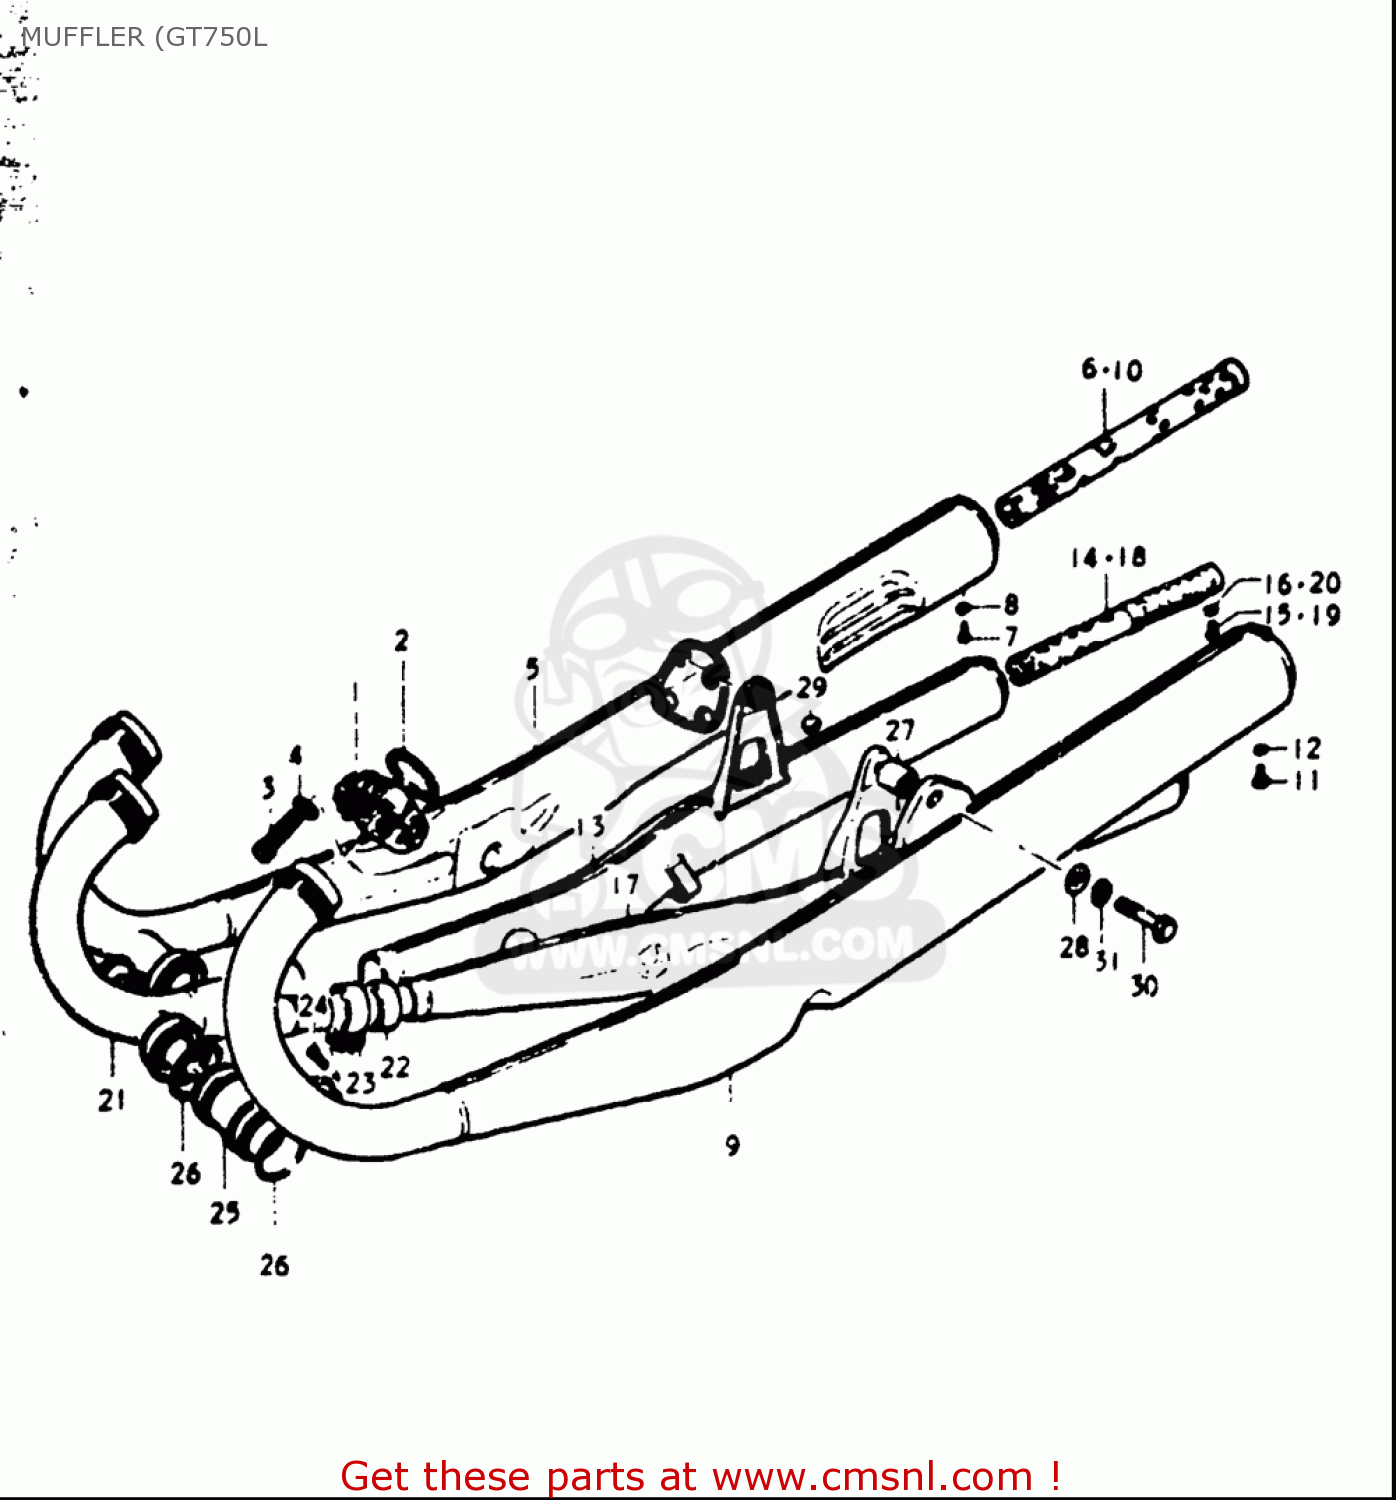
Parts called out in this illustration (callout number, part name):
2	GASKET,EXHAUST PIPE (NAS)
3	BOLT
4	WASHER,LOCK
6	PIPE,BAFFLE
7	SCREW(5X12)
8	WASHER,LOCK
10	PIPE,BAFFLE
11	SCREW(5X12)
12	WASHER,LOCK
14	PIPE,BAFFLE CTR
15	SCREW(5X12)
16	WASHER,LOCK
18	PIPE,BAFFLE CTR
19	SCREW(5X12)
20	WASHER,LOCK
22	CONNECTOR,MUFFLER
23	CLAMP
24	SCREW
26	O RING(D:2.6,ID:39.7)
27	BUSH
28	WASHER
29	CUSHION
30	BOLT
31	WASHER,LOCK
